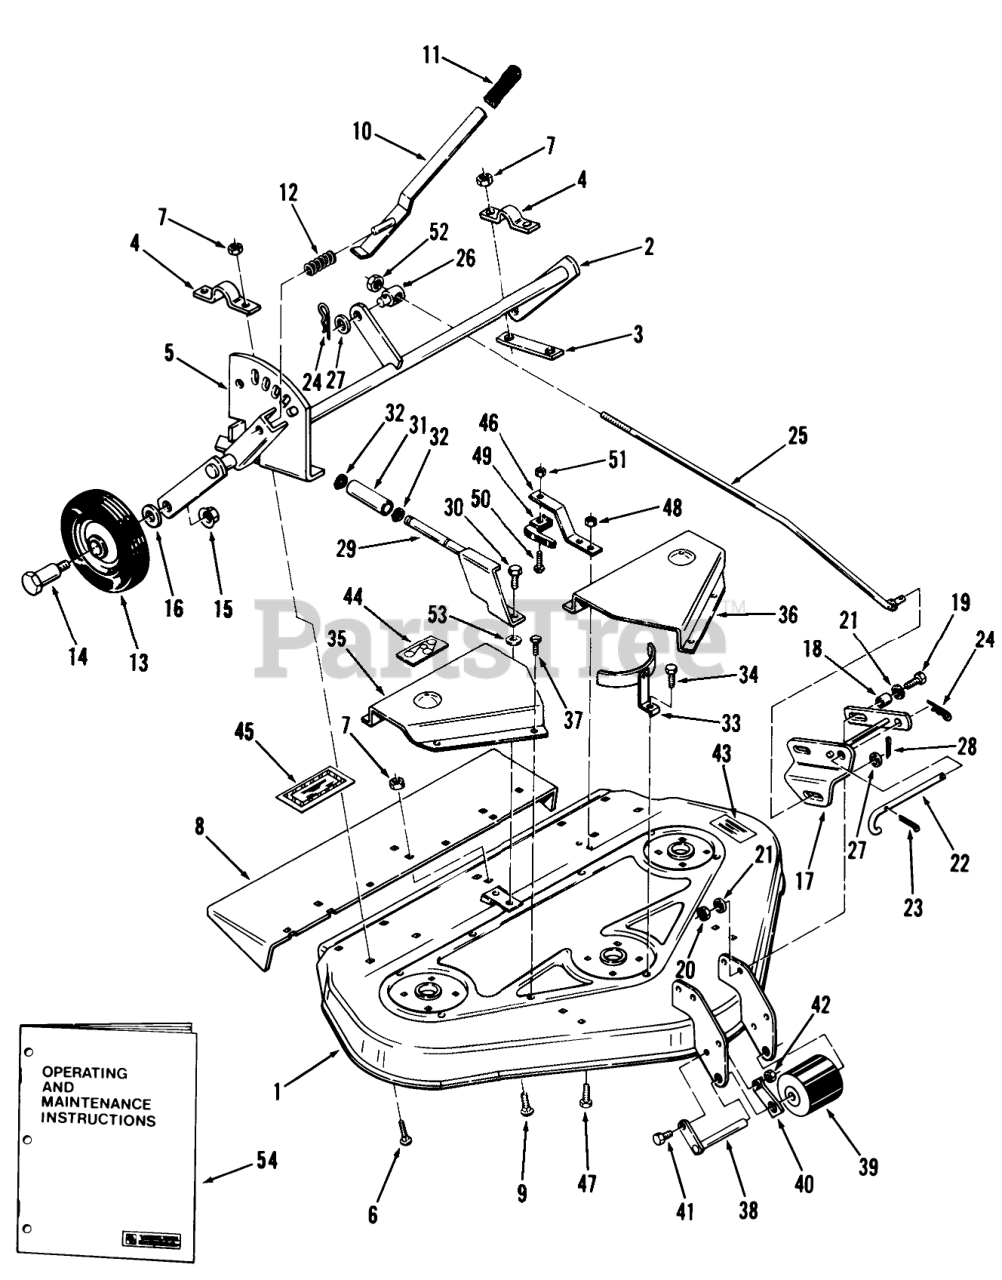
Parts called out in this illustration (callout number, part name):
1	Mower Deck for 95-36YR01
1	ASSY-MOWER DECK 3 R
2	Gage Wheel Support
3	Strap
4	CLAMP
5	QUADRANT R (NS)
6	Bolt
7	Nut
8	Chute Extension
9	Bolt-Carriage
10	Lever
12	SPRING-COMPRESSION
13	Wheel 6 X 1.25
15	Nut
16	SHIM-WASHER
17	FRT SUPT ASSY
18	SPACER
19	Bolt
20	Nut
21	Washer
22	"J" Pin
23	Cotter Pin
24	Hairpin
25	Leveling Rod
26	TRUNNION-LIFT
27	Washer
28	Pop Rivet
29	ASSY-SUPPORT R
30	Bolt
31	SPACER
32	Snap Ring
33	Belt Guard (Front)
34	Bolt
35	Belt Cover R.H.
35	Belt Cover RH
36	Belt Cover L.H.
36	Cover-Belt
37	Bolt
38	Roller Shaft
39	Roller
40	SPRING ROLLER STOP
41	H H C S
42	Nut
43	Caution Decal
44	Decal-Height & Belt Adjustment
45	Decal-Caution
46	Switch Support Bracket
47	H H C S
48	Nut
49	SWITCH
50	Fillister Hd. Screw #8-32 x 1
51	Hex Nut
52	NUT
53	WASHER
54	Owners Manual (Alternate 810108R1)
54	Operating and Maintenance Instructions for 95-32XS01
